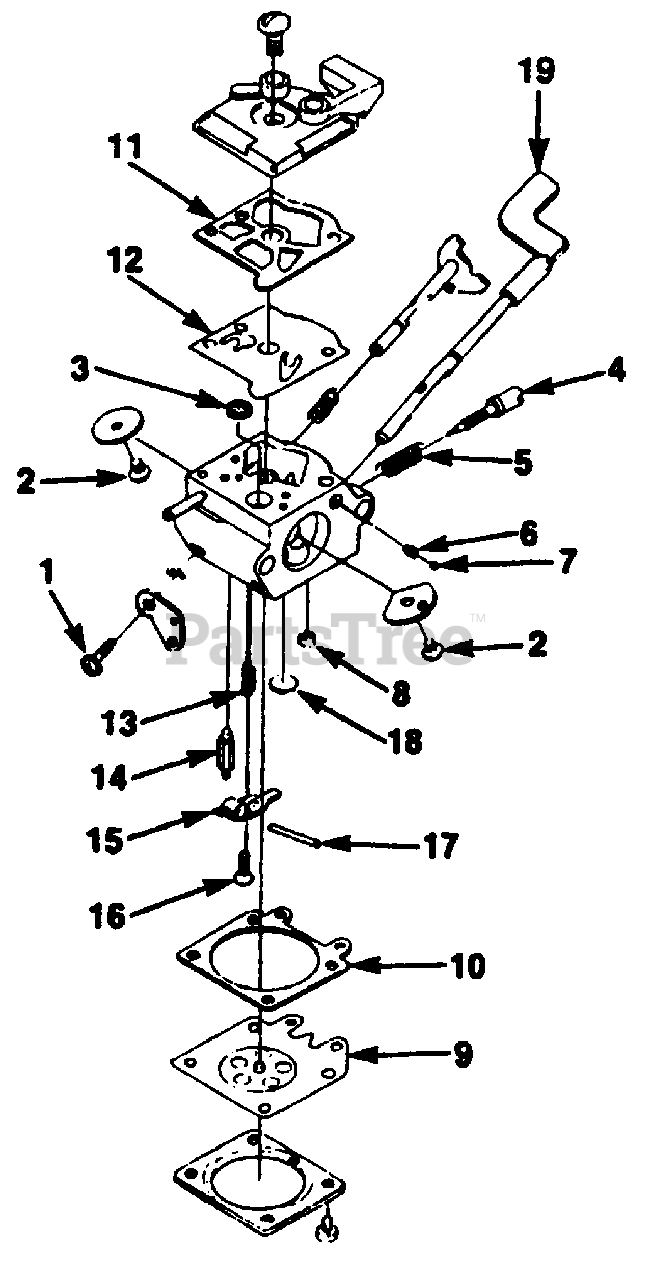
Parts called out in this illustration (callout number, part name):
1	Repair Kit (Includes 1-18)
2	Repair Kit (Includes 1-18)
3	Repair Kit (Includes 1-18)
4	Repair Kit (Includes 1-18)
5	Repair Kit (Includes 1-18)
6	Repair Kit (Includes 1-18)
7	Repair Kit (Includes 1-18)
8	Repair Kit (Includes 1-18)
9	Repair Kit (Includes 1-18)
10	Repair Kit (Includes 1-18)
11	Repair Kit (Includes 1-18)
12	Repair Kit (Includes 1-18)
13	Repair Kit (Includes 1-18)
14	Repair Kit (Includes 1-18)
15	Repair Kit (Includes 1-18)
16	Repair Kit (Includes 1-18)
17	Repair Kit (Includes 1-18)
18	Repair Kit (Includes 1-18)
19	Choke lever & Rod
